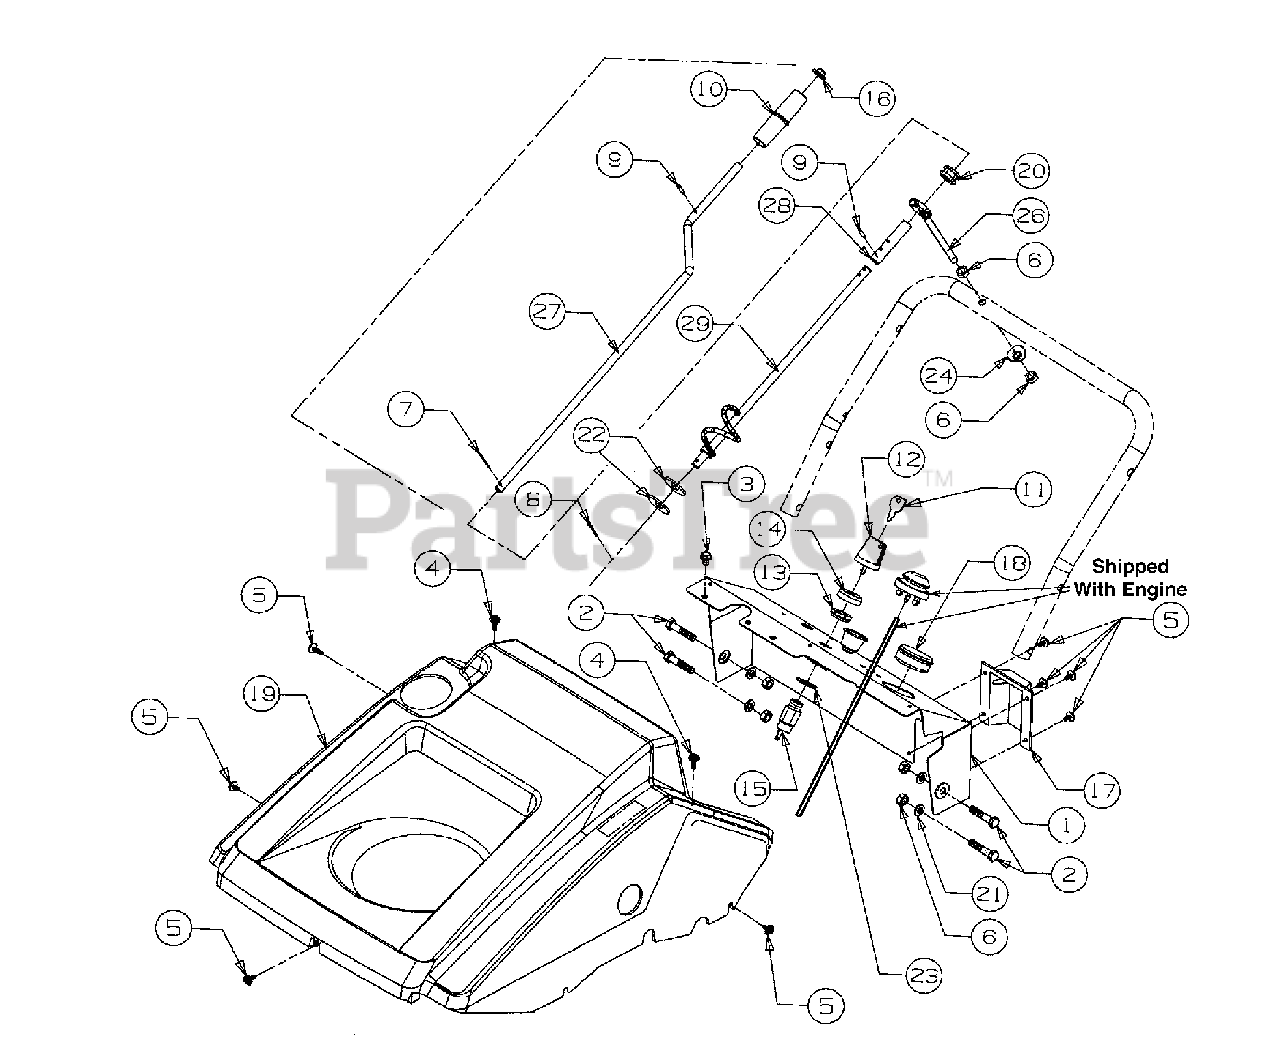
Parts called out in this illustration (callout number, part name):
3	Hex Washer Screw
4	Hex Screw
5	Hex Screw
6	Hex Nut
7	Hairpin Clip
8	Cotter Pin
11	Ignition Key
12	Ignition Key with Logo
13	Nut, Ignition Switch
14	Cover, Ignition Switch
15	Switch-Key
16	Push Cap
17	Choke Cover
18	Plug-Insert
19	Shroud, Black
20	Grommet, Rubber
21	Lock Washer
23	Internal Lock Washer
24	Saddle Washer
26	Eyebolt, Chute Crank
28	Spacer
